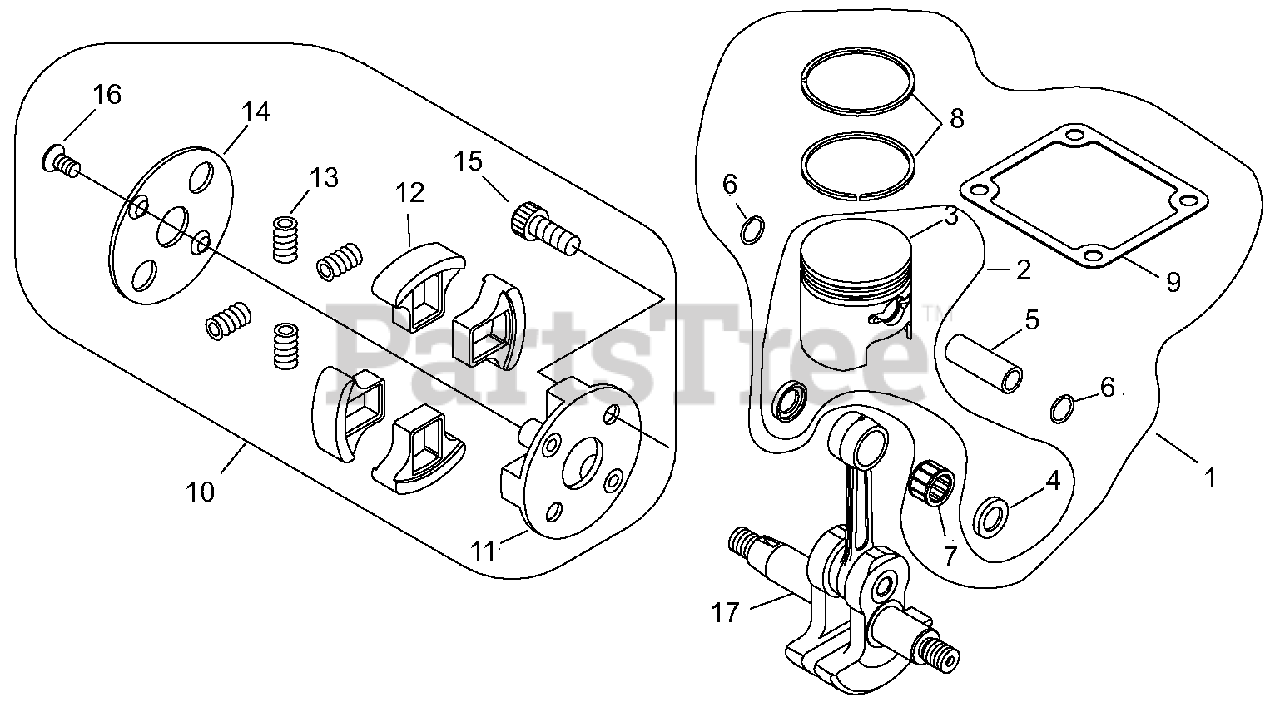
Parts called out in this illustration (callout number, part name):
1	PISTON KIT
2	PISTON SET
3	PISTON
4	SPACER, PISTON
5	PIN, PISTON
6	RING, RETAINING
7	BEARING, NEEDLE - 11
8	RING, PISTON
9	GASKET, CYLINDER
10	CLUTCH ASSY
11	HUB, CLUTCH
12	SHOE, CLUTCH
13	SPRING, CLUTCH
14	PLATE, CLUTCH
15	BOLT, CLUTCH
16	SCREW
17	CRANKSHAFT ASSY
